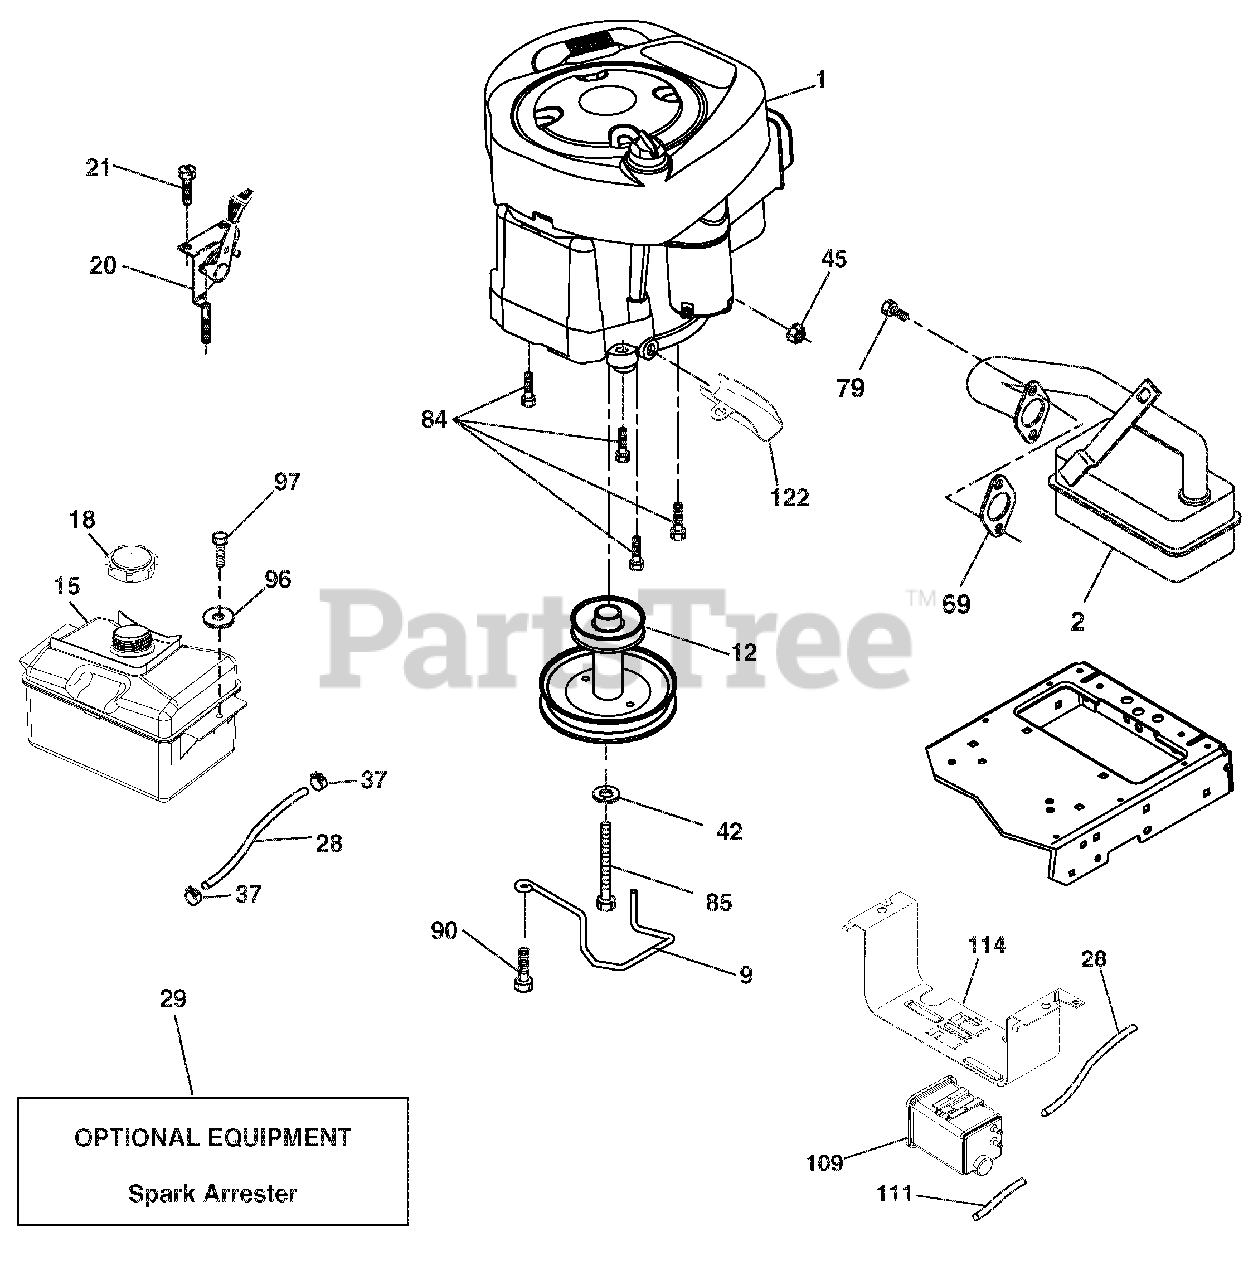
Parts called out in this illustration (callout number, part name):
1	ENGINE BRIGGS MODEL NO. 31P677-1373-B1(ORDER PARTS FROM ENGINE MANUFACTURER)
2	Muffler Exhaust B&S
9	KEEPER.BELT.ENGINE.3.25"NSTL
12	PULLEY.ENGINE
15	TANK ASM.FUEL.1.50.CARB.CA.SVC
18	CAP FUEL
20	CONTROL.TH/CK.COBRA.BS.EEC.428
28	LINE.FUEL.22"FRONT.EMIS.CA.LP
29	KIT.SPARK ARRESTOR(392390 B&S)
37	CLAMP.HOSE.BLK.
42	WASHER.LOCK.HVY HLCL.SPR.7/16
45	Nut, Keps Hex 1/4-20 unc
69	Gasket Eng 1 313 Id Tin Plated
79	SCREW.SOCKET HD.5/16-18 X .75
84	Screw 3/8-16 x <
85	BOLT.HEX.7/16-20X4XGR5-1.5THR.
90	SCREW.3/8-16X1.SMGML.TAP/R.BLK
96	WASHER.9/32 X 7/8 X 16GA.
97	SCREW.HEXWSH.THDROL.1/4-20X3/4
109	CANISTER.CARBON.FILTER ASM.TEX
111	PURGE.LINE.CARB
114	CRADLE.CANISTER.CARBON
122	Extension Drain Oil
